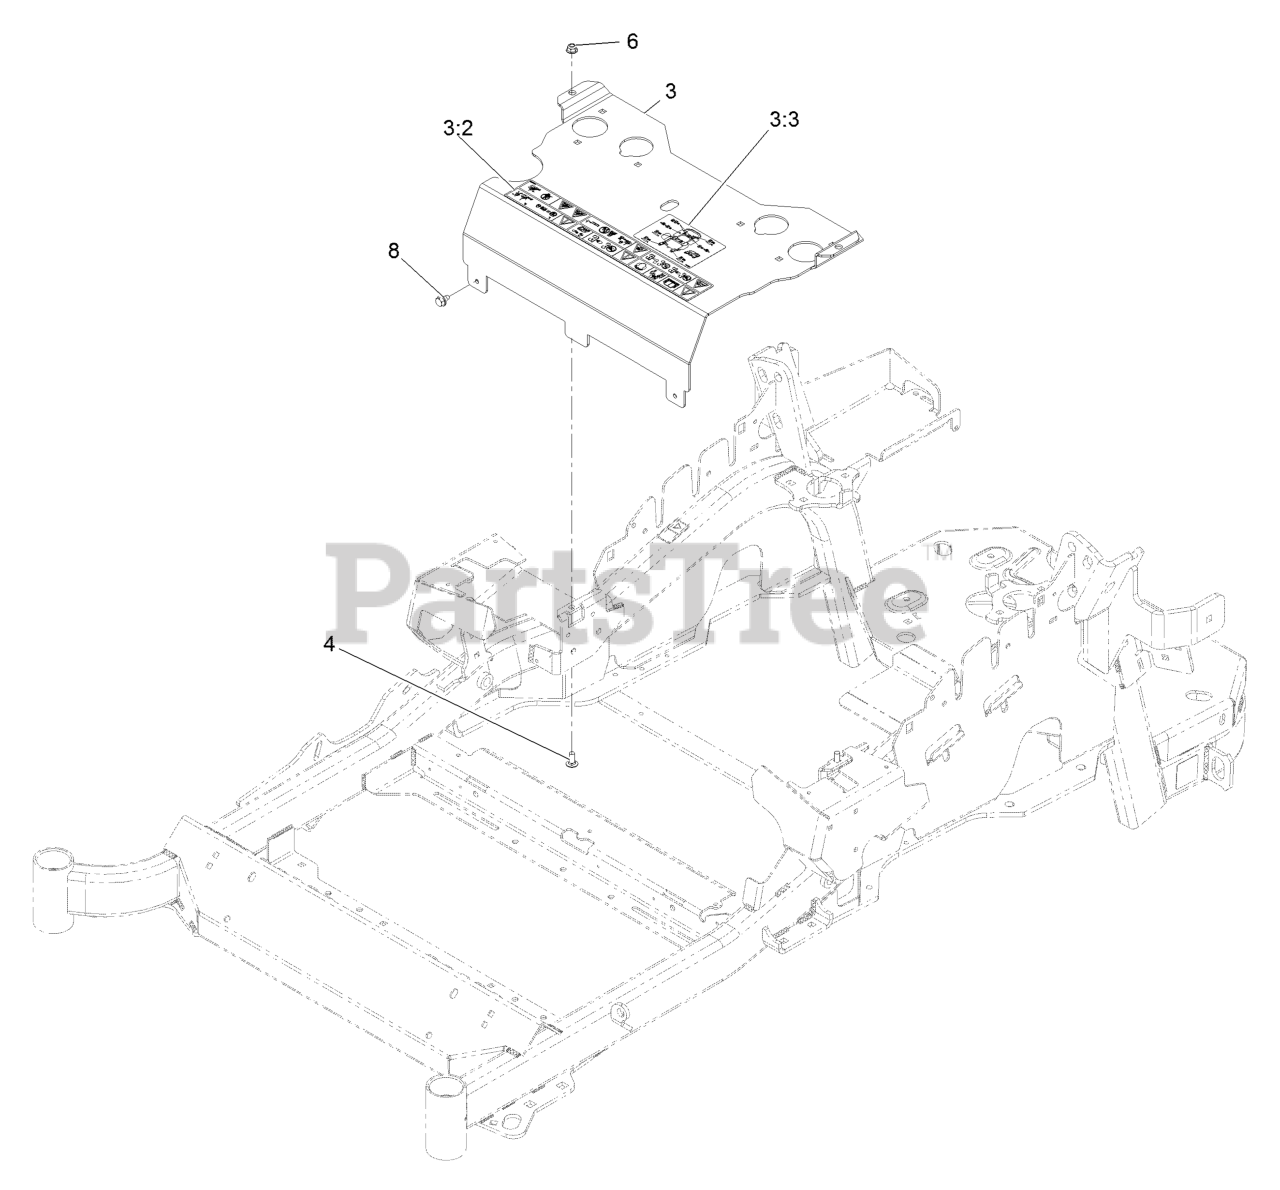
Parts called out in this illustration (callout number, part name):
3	MOUNT-SEAT
3:2	DECAL-CONSOLE
3:3	DECAL-SERVICE AID
4	SCREW-CARR
6	NUT-HF, NI
